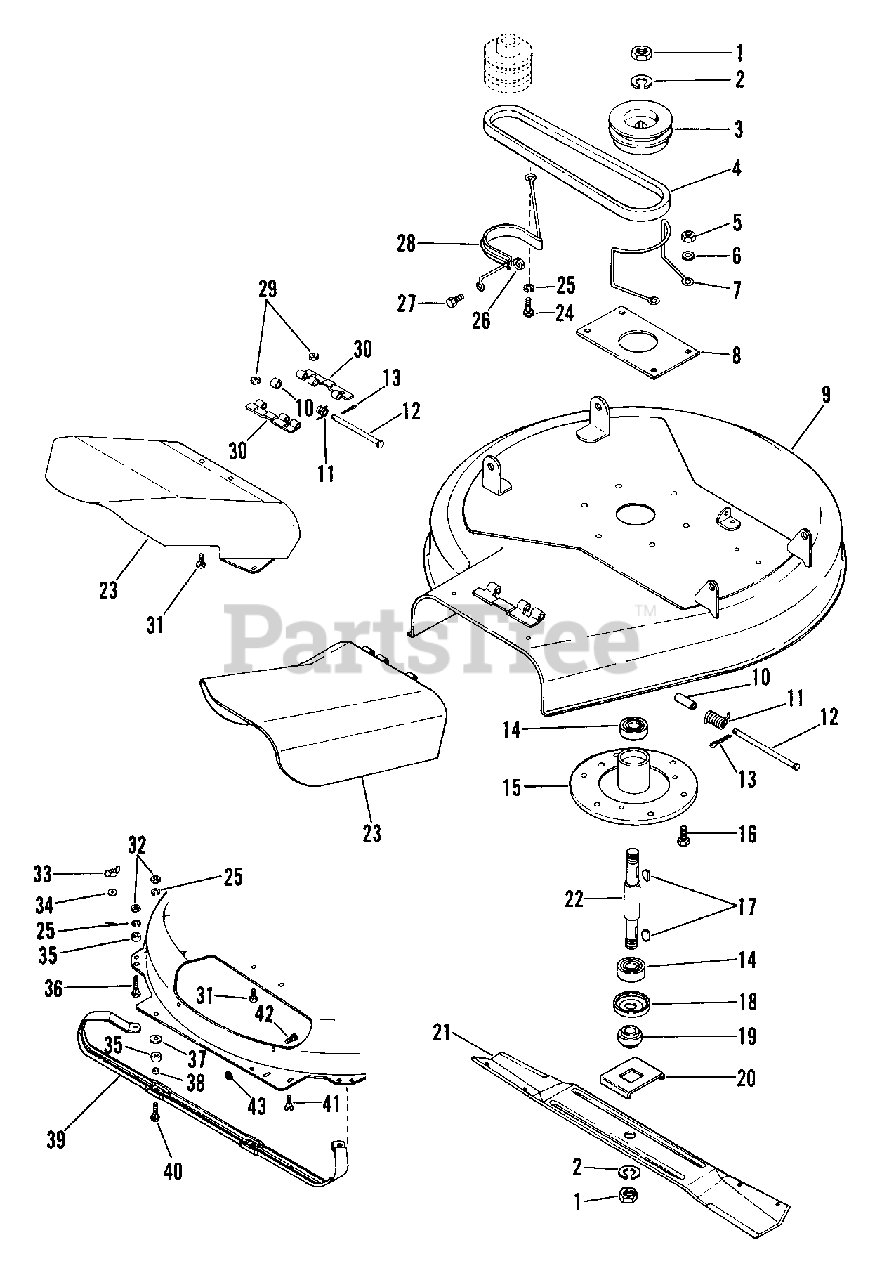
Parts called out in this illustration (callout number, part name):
1	NUT-JAM .75-10 PL
2	WSHR-LK .750X.188 MED PL
3	MOWER SHEAVE
4	V-BELT, 5L-RAW EDGE
4	V-BELT, HB-RAW EDGE
5	NUT-LK-CTR .375-16 GR A PL
6	WSHR-FL-STL .38X.875X.083 PL
7	MOWER BELT FINGER
9	MOWER PAN ASSEMBLY
9	MOWER PAN ASSEMBLY 28"
10	BSHG-SLV .334 X .502 X 1.437
11	SG-TORS .095X.50X 1.0
11	SG-TORS .090X.37X.63
12	CLEVIS PIN
13	PIN-COTR .09X.75 PL
14	BRG-BALL .750X1.781X.61
15	SPINDLE HOUSING
16	BLT-HEX .38-16X1.00 PL
17	KEY-WDRF .188X.75X.313 SAE 9
18	BEARING SLINGER
19	RETAINER HUB
20	BLADE TRAY
21	MOWER BLADE 26
21	MOWER BLADE 28
22	SPINDLE SHAFT
23	PAN CHUTE EXTENSION
23	DISCHARGE CHUTE
24	BLT-HEX .31-18X1.00 PL GR 2
25	WSHR-LK .312X.097 PL HVY
26	NUT-LK .312-18 GR A PL
27	BLT-SERHFWH .31-18X.62 PL
28	REAR BELT FINGER
29	NUT-LK-CTR .250-20 PL
30	HINGE PLATE
31	BLT-RDHDSQNK .25-20X.62 PL
32	NUT-HEX .312-18
33	NUT-WING .250-20
34	WSHR-FL-STL.281X.62X.065 PL
35	SPACER .328X.750X.375
36	BLT-RDHDSQNK .31-18X1.75 SHTPL
37	WSHR-FL-STL .328X1.0X.094
38	SPACER BUSHING .5 X .32 X .21
39	28 IN ADJUSTABLE SKID
40	BLT-RDHDSQNK .31-18X1.25 SHTPL
41	BLT-RDHDSQNK .25-20X1.00 GR5
42	BLT-RDHDSQNK .312-18X.62SHTPL
43	NUT-PUSH .312
